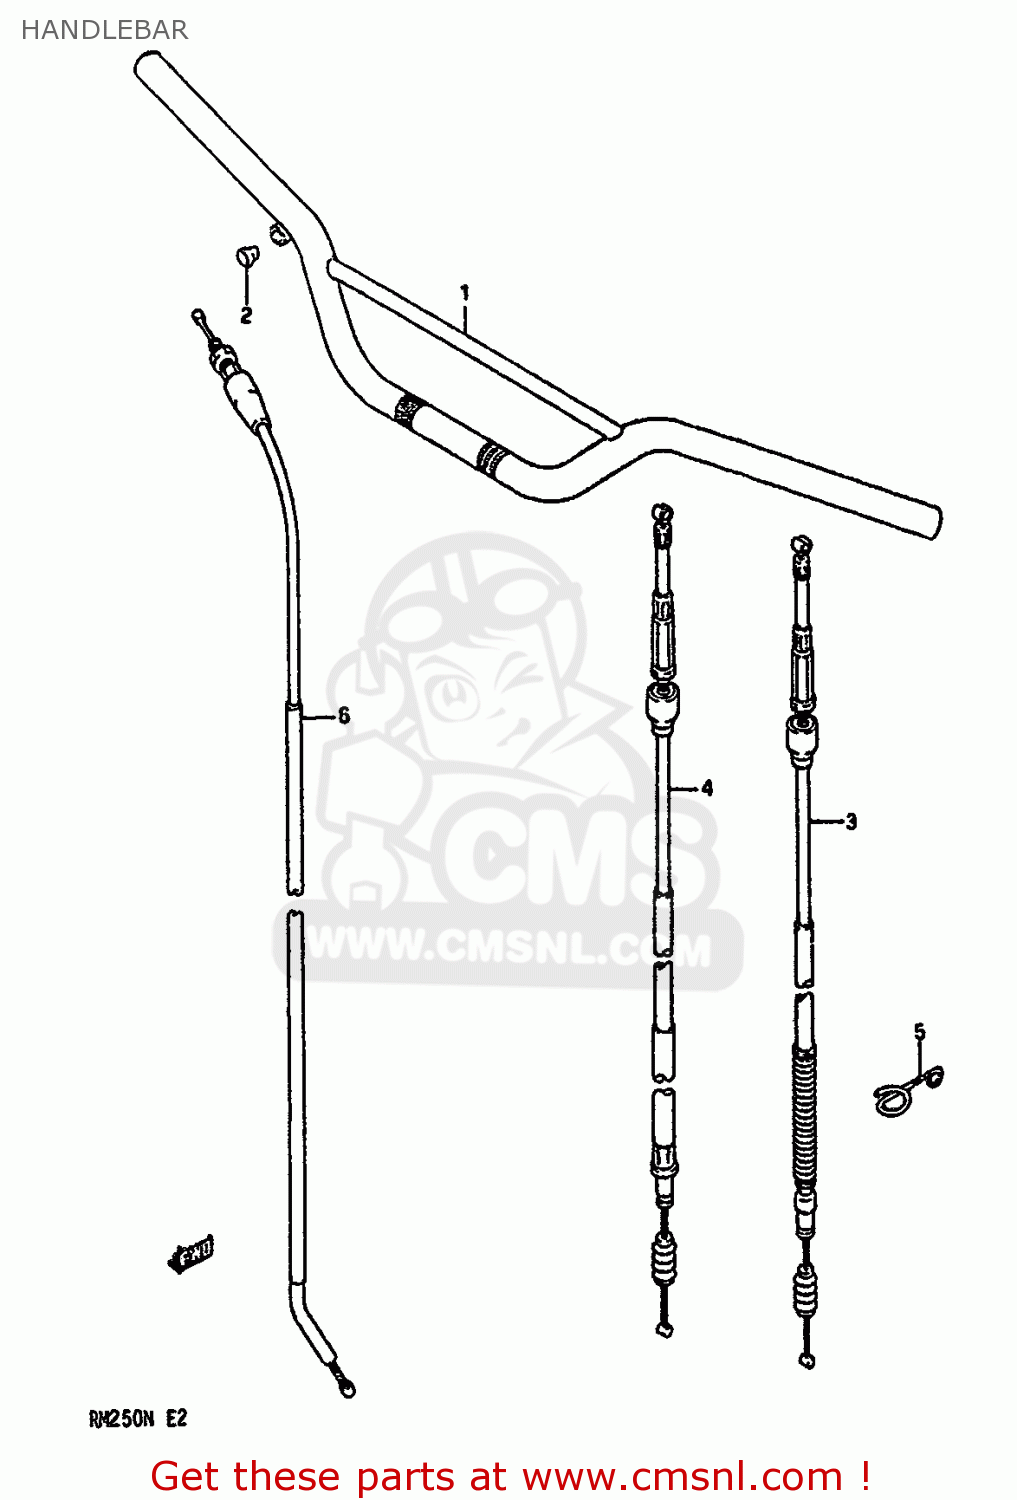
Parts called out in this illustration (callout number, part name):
1	HANDLEBAR
2	CAP(OD:14)
3	CABLE ASSY,CLUTCH
4	CABLE ASSEMBLY,CLUTCH
5	GUIDE,CLUTCH CABLE
6	CABLE ASSY,THROTTLE
